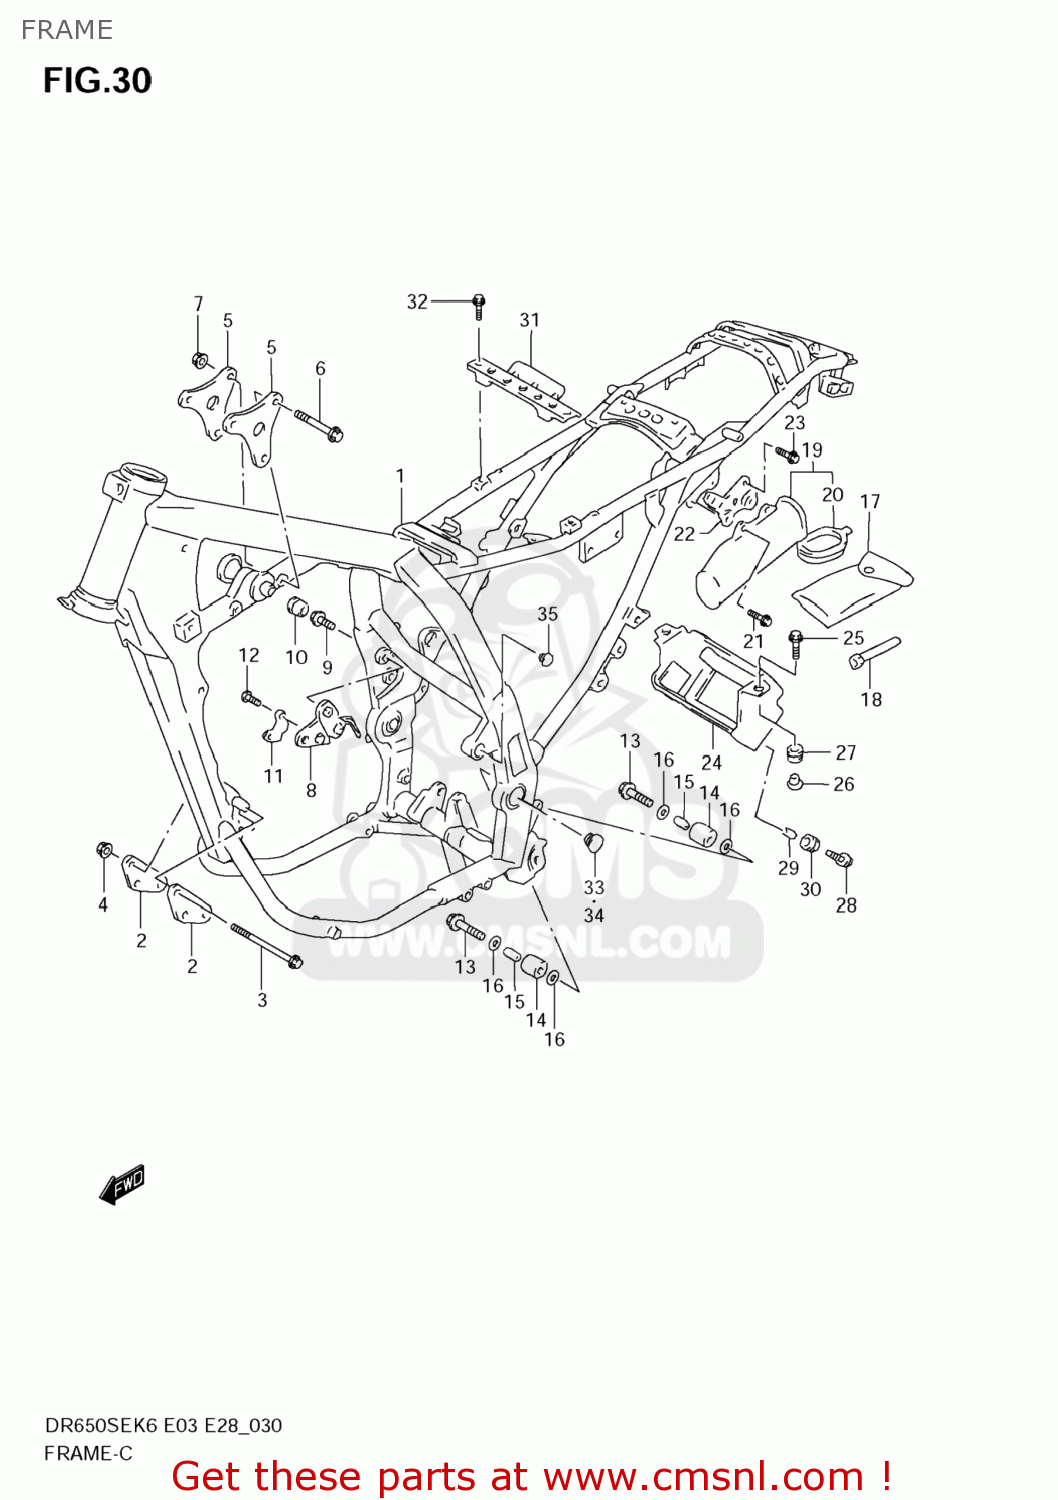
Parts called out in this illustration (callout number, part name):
1	FRAME(SILVER)
2	PLATE,ENG MTG FR
3	BOLT(8X100)
4	NUT
5	PLATE,ENG MTG UPR
6	BOLT(8X55)
7	NUT
8	PLATE,ENG MTG RR,R
9	BOLT
10	PLUG(OD:22)
11	BRACKET,STOP SWITCH
12	SCREW
13	BOLT(8X38)
14	ROLLER,CHAIN CONTROL UPR
15	SPACER(8.6X12X25.5)
16	WASHER
17	TOOL ASSY
18	SPARK PLUG WRENCH(16)
19	HOLDER,TOOL
20	CAP,HOLDER
21	BOLT(6X16)
22	BRACKET,TOOL HOLDER
23	BOLT
24	HOLDER,BATTERY
25	BOLT(6X20)
26	WASHER
27	CUSHION
28	BOLT(6X16)
29	SPACER(6.1X9X7.5)
30	CUSHION
31	PLATE,BATTERY FITING
32	BOLT
33	PLUG,FRAME PIVOR,R
34	PLUG,FRAME PIVOR,L
35	PLUG,FRAME BOSS
